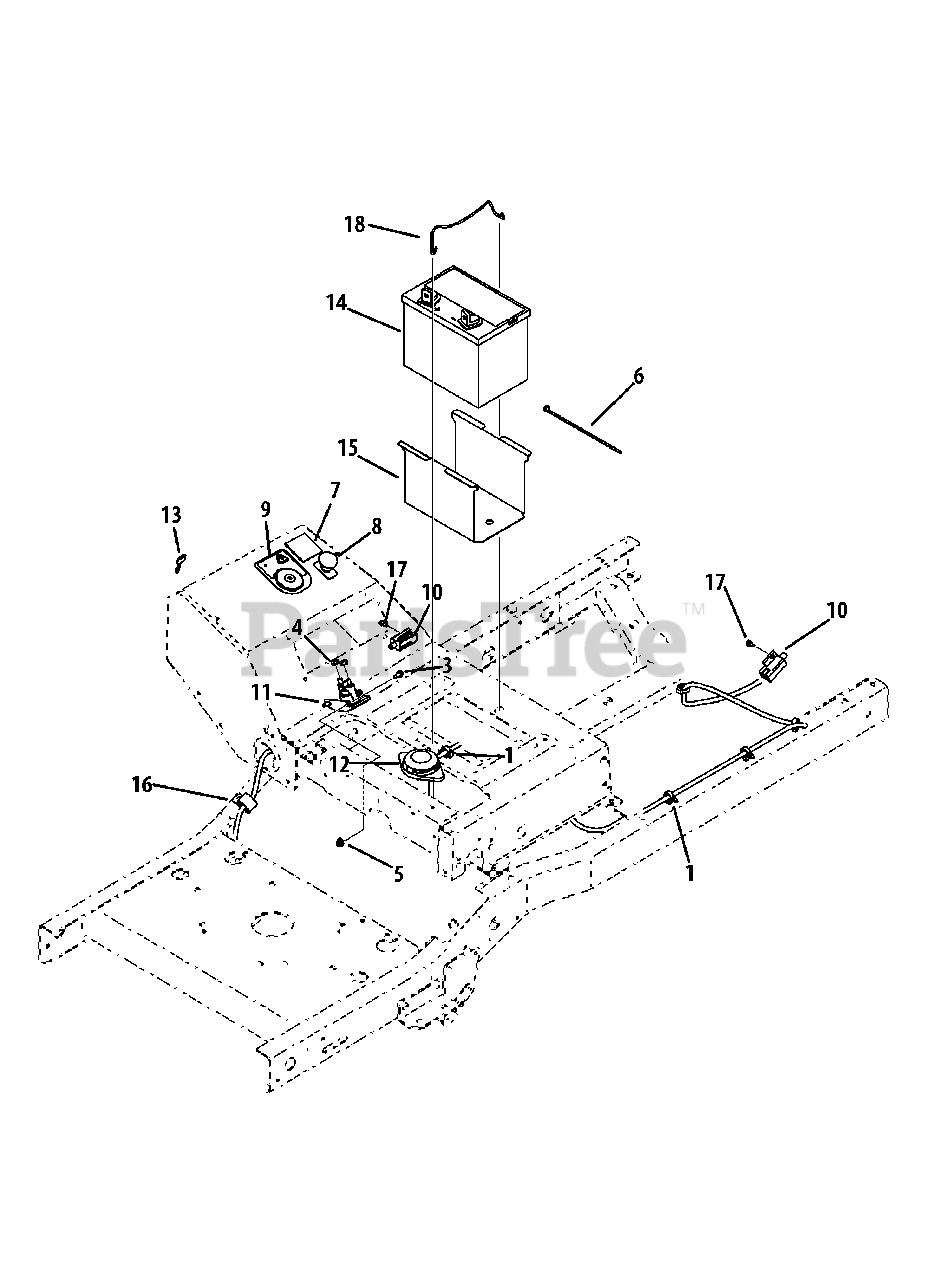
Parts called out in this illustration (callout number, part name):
1	Electrical Conduit Clip, 1/2
3	Hex Washer Screw, 1/4-20 x 0.500
4	Sems Nut, 1/4-20
5	Flange Lock Nut, 1/4-20
6	Cable Tie, 3/16 x .05 x 7.4
7	Hour Meter/Service Minder
8	Electric PTO Switch
9	Key Switch
10	Interlock Switch
11	Solenoid
12	Seat Switch
13	Key, Assembly
16	Clamp, 1.0
17	Shoulder Screw, #10-32 x .500
18	Battery Rod
